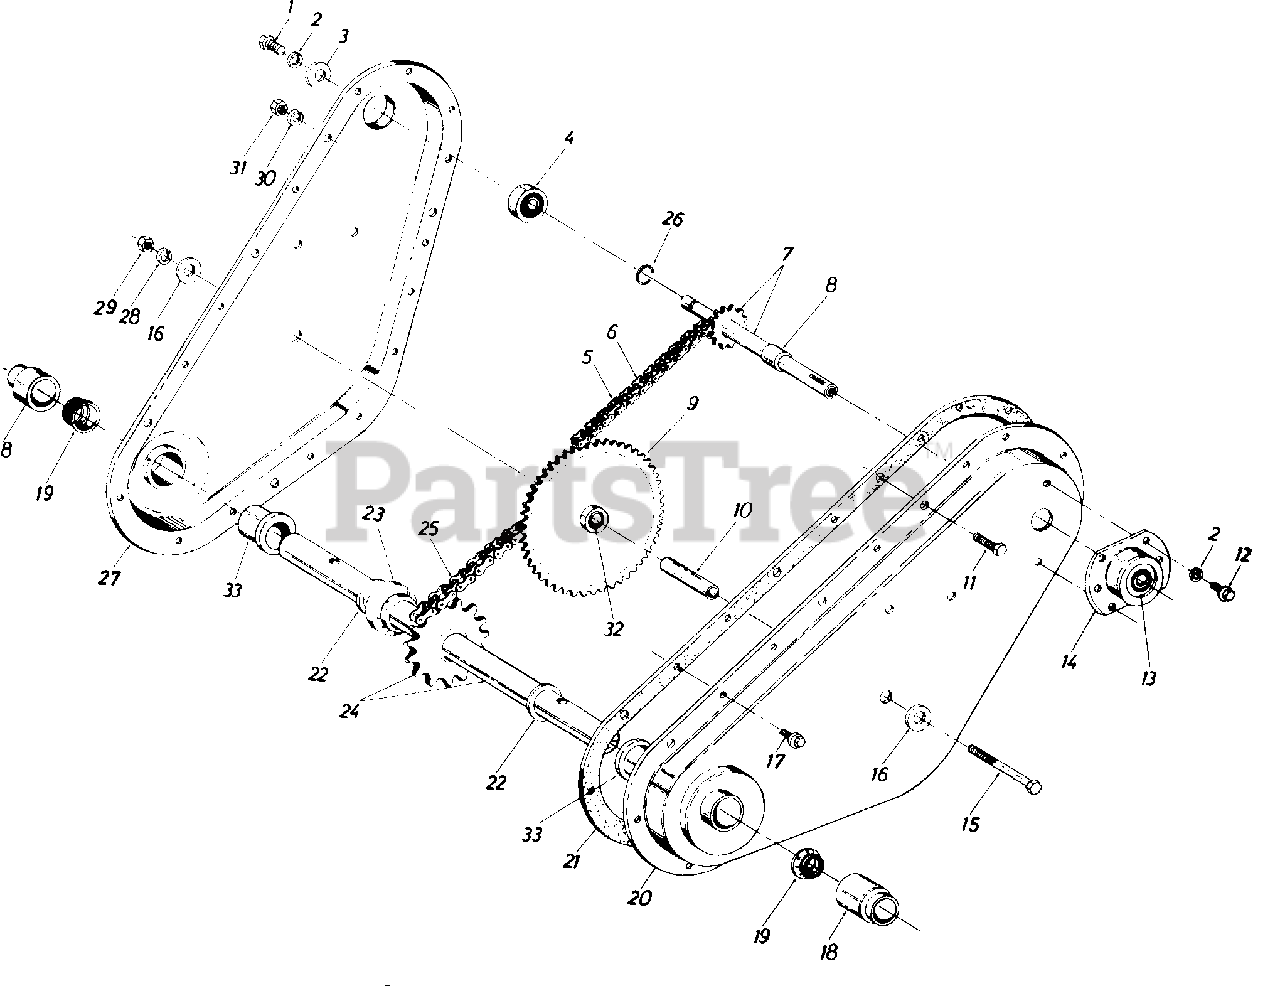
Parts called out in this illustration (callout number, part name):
1	Hex L-Scr. 1/4-28 x .625" Lg.
2	L-Wash. 1/4" I.D.
3	Fl-Wash. .25" I.D. x .93" O.D. x .125" Thk.
4	Bearing .62" I.D. x 1.38" O.D. x .437" Thk.
5	#35 Chain 3/8" Pitch x 52 Links Endless
6	Master Link
7	Input Shaft Assembly
8	Spacer
9	Sprocket Assembly
10	Sprocket Hub Tubing 3/8" I.D. x 5/8" O.D. x 1.9" Lg.
11	Hex Scr. 5/16-18 x .625" Lg."
12	Hex Wash. Hd. Self-Tap Scr. 1/4-20 x .50" Lg.
13	Bearing .625" I.D. x 1.38" O.D. x .437" Thk.
14	Bearing Housing
15	Hex Scr. 3/8-24 x 2.75" Lg.
16	Fl-Wash. 3/8" I.D. x 1.25" O.D. x .100 Thk.
17	Hex Wash. Hd. Self-Tap Scr. 1/4-20 x .50" Lg.
18	Dust Cap
22	Thrust Wash. 1.00" I.D. x .030" Thk.
23	Step Spacer
24	Tine Shaft Assembly
25	#50 Chain 5/8" Pitch x 46 Links Endless
26	Snap Ring
29	Hex Nut 3/8-24 Thd.
30	L-Wash. 5/16" Scr.
31	Hex Nut 5/16-18 Thd.
32	Beari ng
33	Bearing
